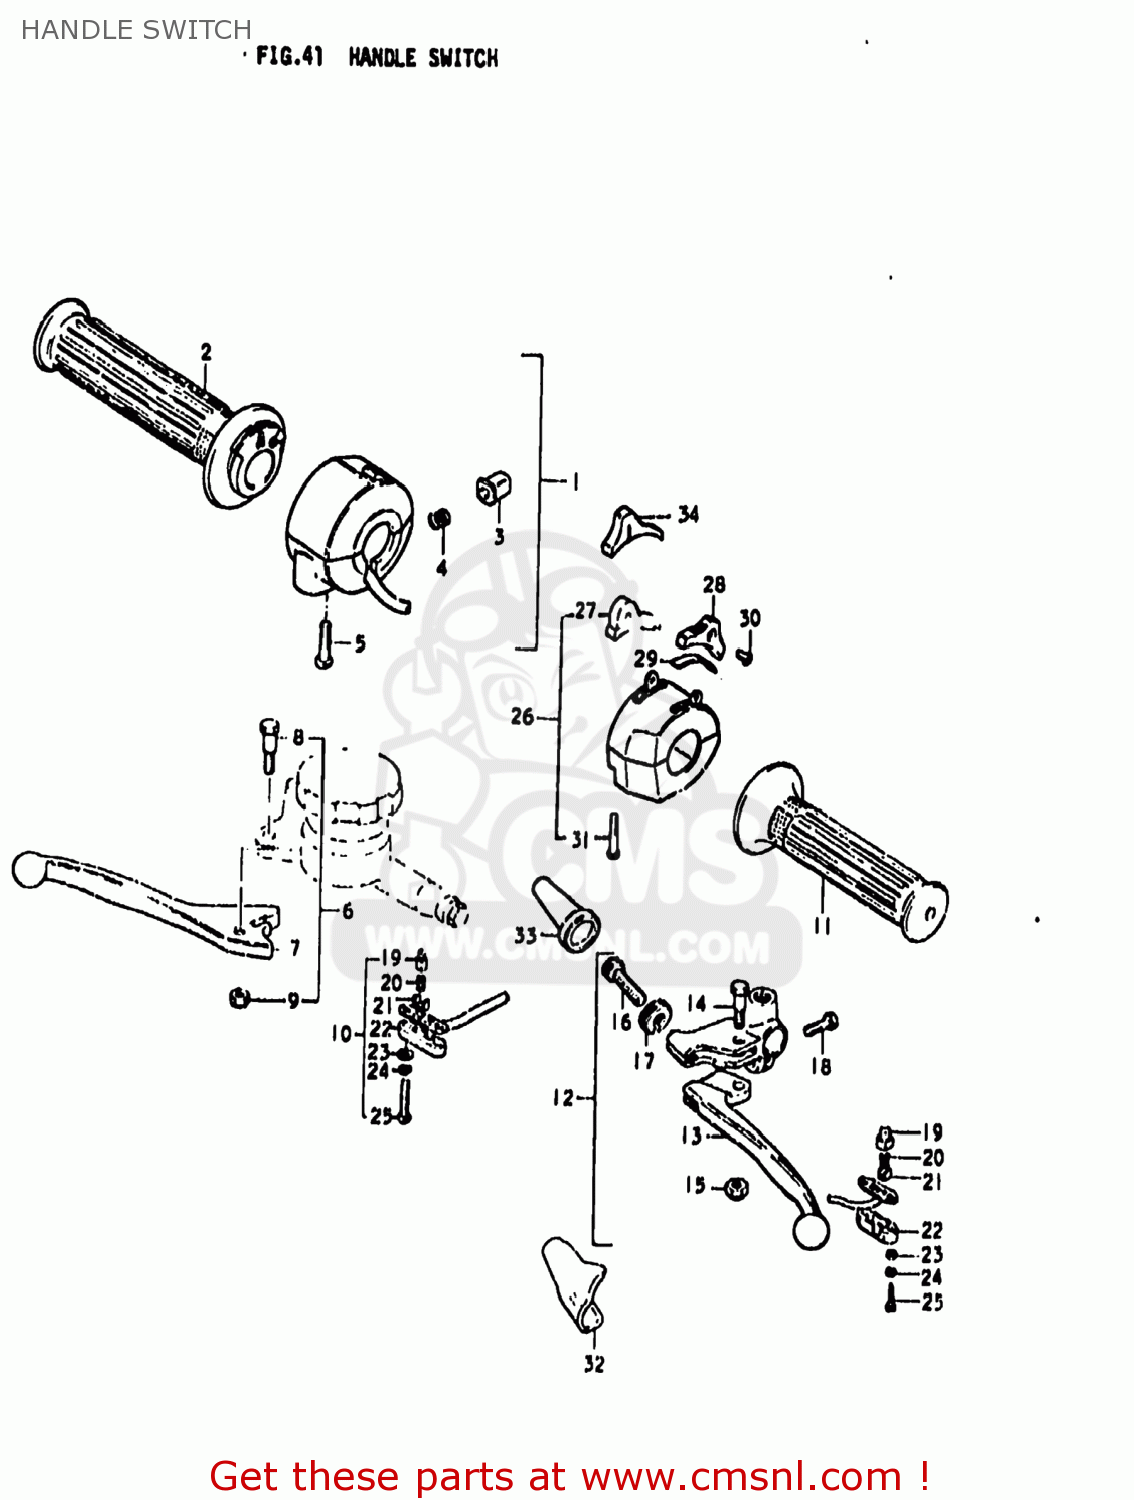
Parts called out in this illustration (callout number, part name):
1	CASE ASSEMBLY,THROTTLE
2	GRIP,THROTTLE
3	BUTTON
4	SPRING
5	SCREW
6	LEVER ASSEMBLY,BRAKE
7	LEVER,BRAKE
8	BOLT,LEVER
9	NUT 6MM
10	SWITCH ASSY,STOP
11	GRIP,LEFT
12	LEVER ASSEMBLY
13	LEVER,CLUTCH
14	BOLT,LEVER
15	NUT 6MM
16	ADJUSTER,CABLE
17	NUT,CABLE ADJUSTER
18	BOLT
19	HOLDER
20	SPRING
21	PLATE
22	COVER,FR BK TERMINAL BASE
23	WASHER
24	LOCK WASHER
25	SCREW
26	SWITCH ASSEMBLY,HANDLE,LEFT
28	KNOB,DIMMER SWITCH
29	SPRING
30	SCREW
31	SCREW
32	COVER,CLUTCH LEVER
33	BOOT,CLUTCH CABLE
34	KNOB,LIGHTING SWITCH
